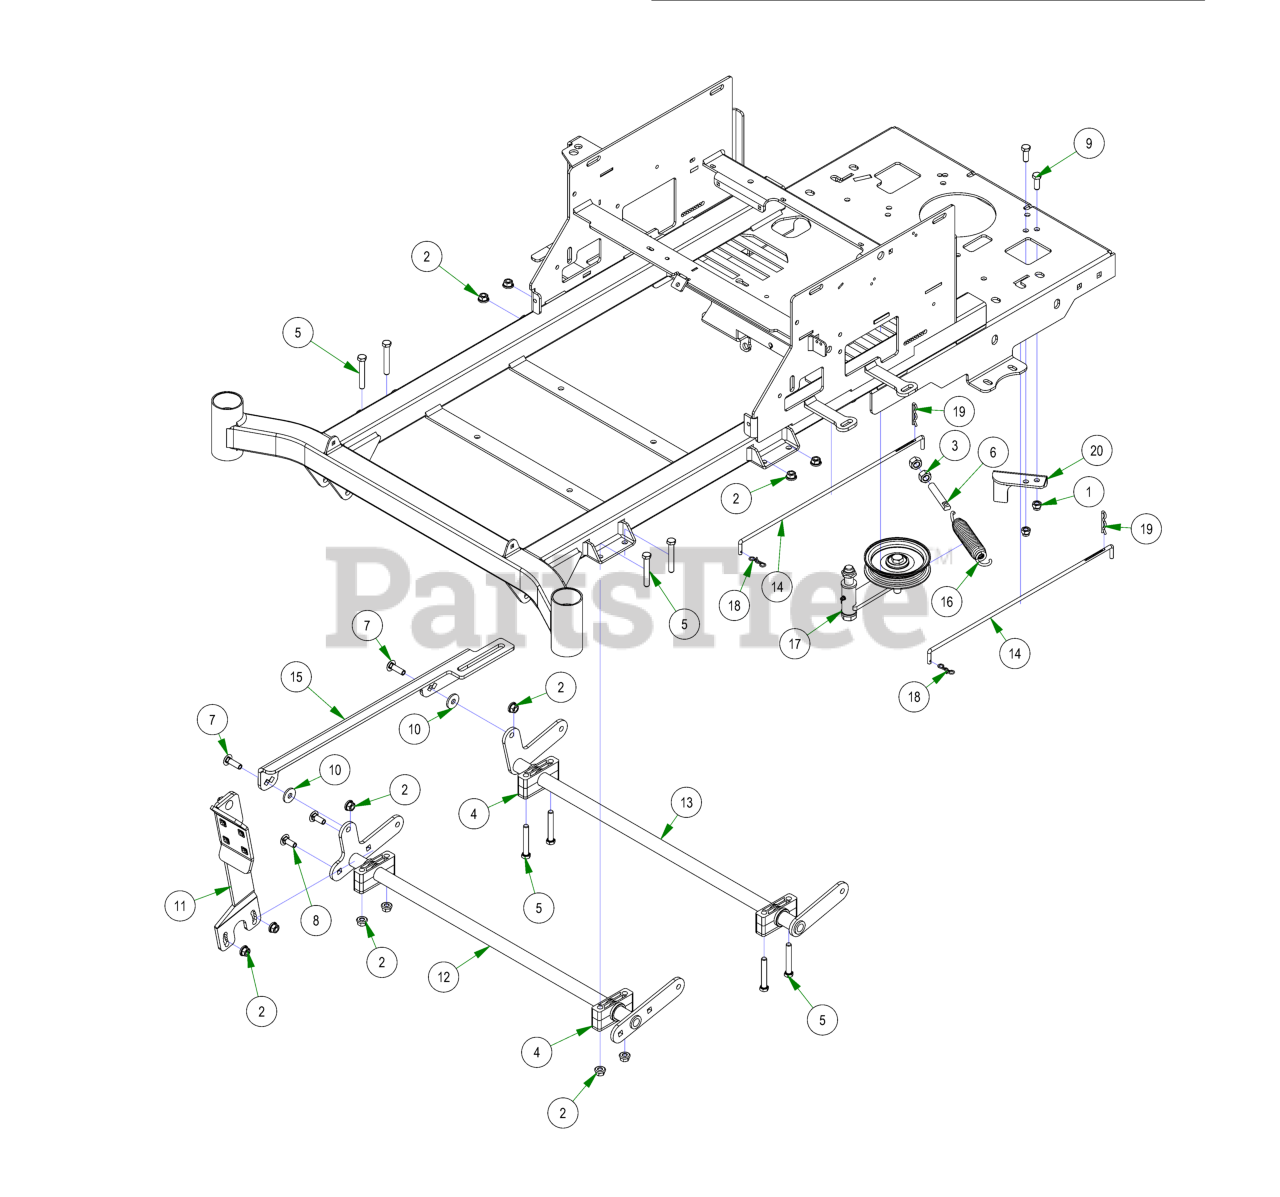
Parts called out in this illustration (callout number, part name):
1	3/8-16 NYLON INSERT LOCKNUT ZINC
2	3/8-16 NYLON INSERT FLANGE LOCKNUT (GR.F) ZINC
3	1/2-13 HEX NUT ZINC
4	Pillow Block Kit
5	3/8-16 X 2-1/2 HEX CAP SCREW (GR.5) ZINC
6	All Thread
7	3/8-16 X 1-1/4 CARRIAGE BOLT ZINC
8	3/8-16 X 1 CARRIAGE BOLT (GR.5) ZINC
9	3/8-16 X 1 GR 5 Hex Bolts Zinc
10	.390 ID X 1.12 OD X .125 THK FLAT WASHER NYLON
11	Foot Pedal Assembly
12	Actuator Bar Front- 2017 MZ/ZT
13	Actuator Bar Rear- 2017 MZ/ZT
14	Neutral Rod
15	2017 MZ/ZT Actuator Linkage
16	Deck Idler Spring
17	ZT Pump Idler
19	Neutral Rod Clip
20	2017 MZ Clutch Stop
21	2024 MZ 42-48 Frame
22	2024 MZ-Avenger 54-60 Frame
